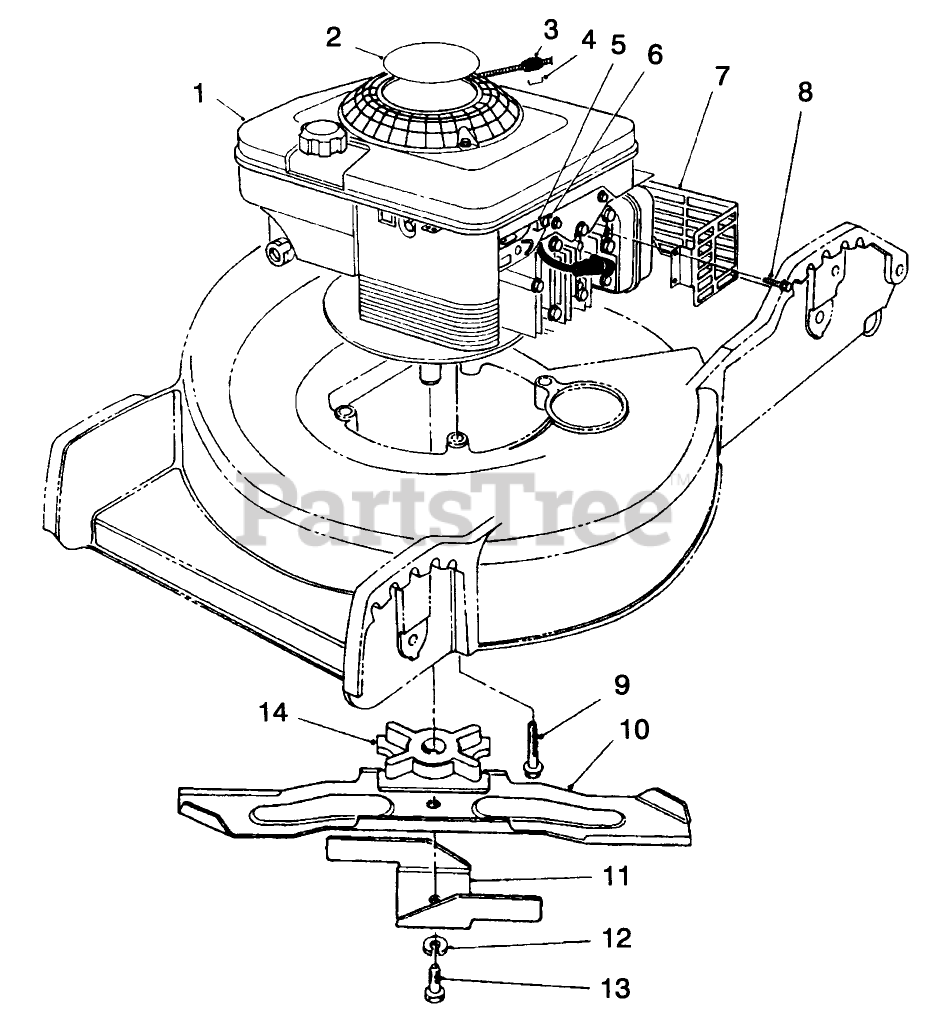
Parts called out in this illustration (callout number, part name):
1	Engine
3	STOP-ROPE
5	CLAMP-CASING
6	CLAMP SCREW F/W ENGINE
7	SHIELD - MUFFLER
11	18 ACCELERATOR *
12	WASHER-LOCK
13	SCREW-HH
14	BLADE RETAINER
